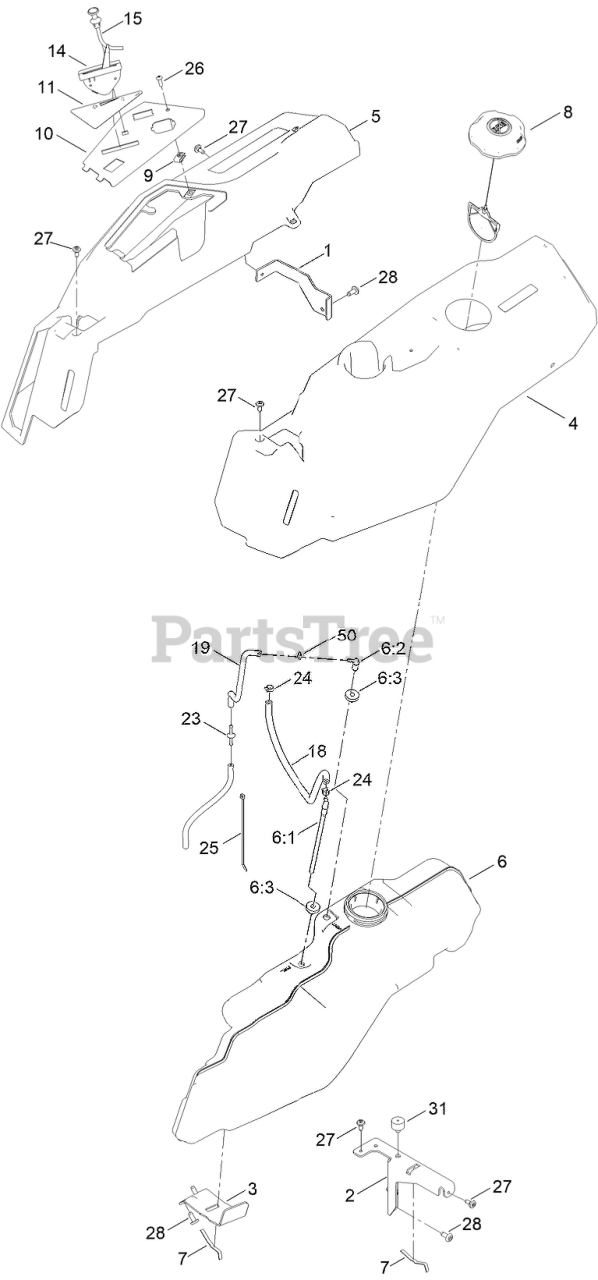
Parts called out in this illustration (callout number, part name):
1	BRACKET-POD
2	SUPPORT-POD, LH
3	SUPPORT-TANK, FUEL
4	POD-LH
5	POD-RH, MYRIDE
6	TANK-FUEL ASM
6:1	CONNECTOR-ELBOW, 90 DEG
6:2	FITTING-ELBOW 90
6:3	BUSHING
7	SPRING
8	CAP-FUEL, RATCHETING
10	PANEL - CONTROL
11	DECAL-PANEL, CONTROL
14	CABLE-THROTTLE
15	CABLE-CHOKE
18	HOSE-FUEL
19	HOSE-FUEL
23	ADAPTER ORIFICE
24	CLAMP-HOSE
25	TIE-CABLE
26	SCREW-PRH
27	SCREW-SHOULDER
31	BUMPER-GROMMET
50	CLAMP-HOSE
